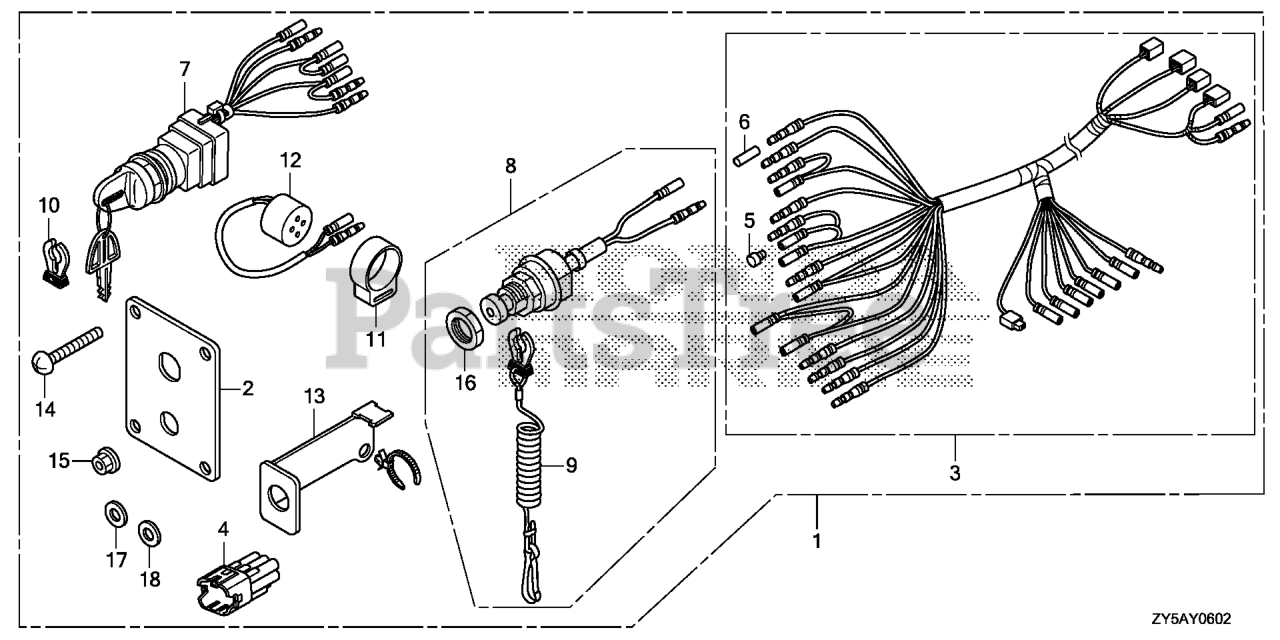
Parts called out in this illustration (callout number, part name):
1	PANEL KIT, SWITCH (SINGLE)
1	PANEL KIT, SW
2	PANEL, CONTROL (SINGLE)
3	HARNESS ASSY., SWITCH PANEL
4	DUMMY, WATERPROOF CONNECTOR (GREEN)
5	PLUG, CONNECTOR (INNER) (TROLLING CONTROL)
6	PLUG, CONNECTOR (OUTER) (ENGINE NO.)
7	SWITCH ASSY., COMBINATION
8	SWITCH ASSY., EMERGENCY STOP (SINGLE)
9	WIRE, EMERGENCY
10	CLIP, EMERGENCY LOCK
11	SUSPENSION, AUDIBLE PILOT
12	BUZZER, WARNING
13	BRACKET
14	SCREW, PAN (5X40) DUAL QTY = (8) (SINGLE)
15	NUT, FLANGE (5MM)
16	NUT
17	WASHER, PLAIN (5MM)
18	WASHER, SPRING (5MM)
18	WASHER, SPG (5MM)
